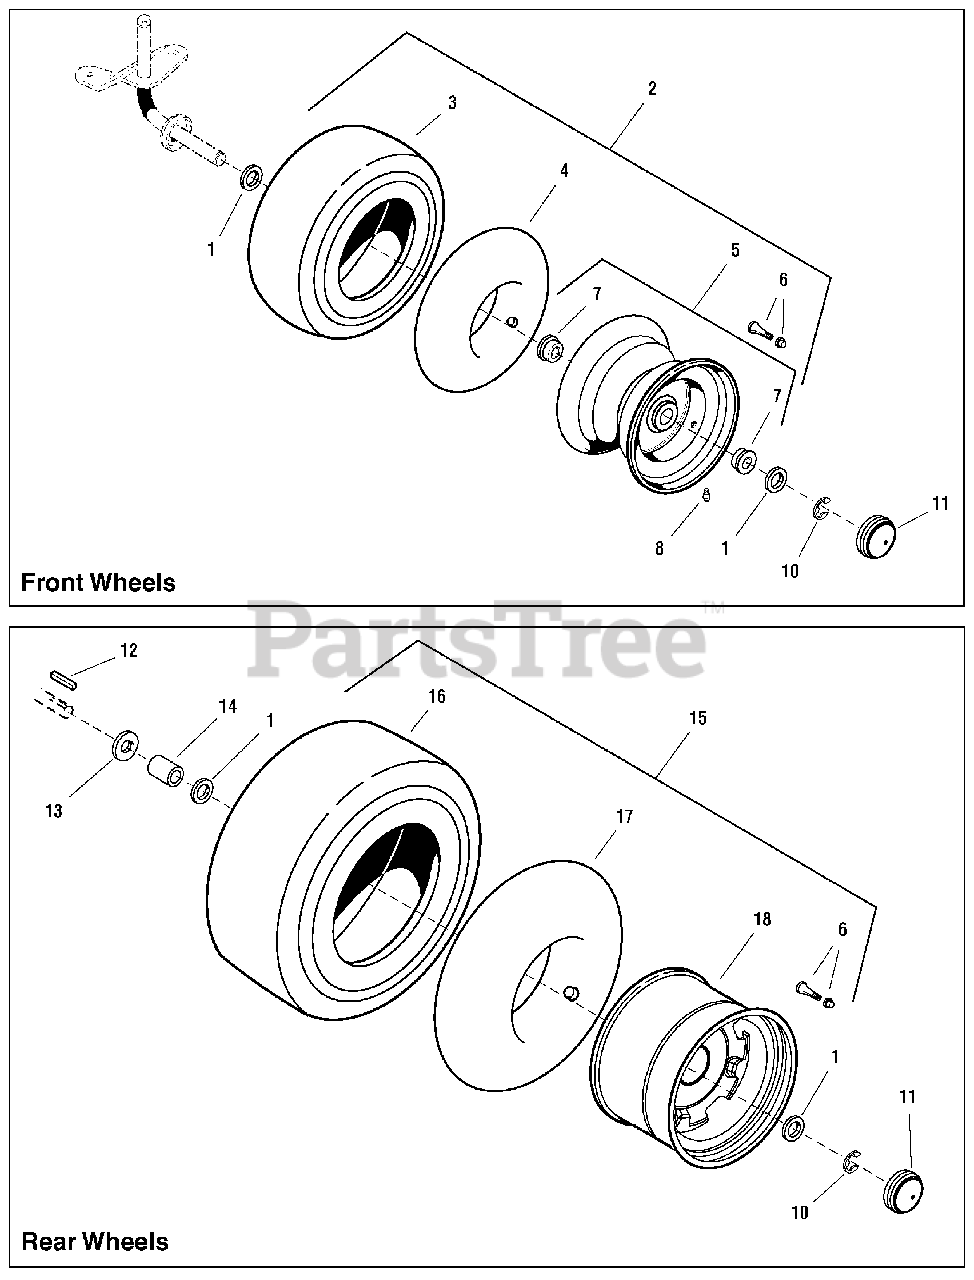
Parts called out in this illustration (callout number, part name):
1	WASHER, 3/4
2	WHEEL & TIRE ASSEMBLY, Front
3	TIRE, Turf 15 X 6.00 - 6 Saver TL
4	TUBE, Tire, Front
5	WHEEL & BUSHINGS ASSEMBLY, Front
6	VALVE STEM & CAP
7	BEARING
8	FITTING, Grease, 1/4-28 Thread
10	RING, Retaining
11	CAP, Hub
12	KEY, 3/16 x 3/16 x 3
13	WASHER
14	SPACER, 0.77 ID x 1-1/4 OD x 1-5/8
15	WHEEL & TIRE ASSEMBLY, Rear 20"
16	TIRE, K358, 20 X 8-8
17	TUBE, Tire, Rear
18	WHEEL, Hub
